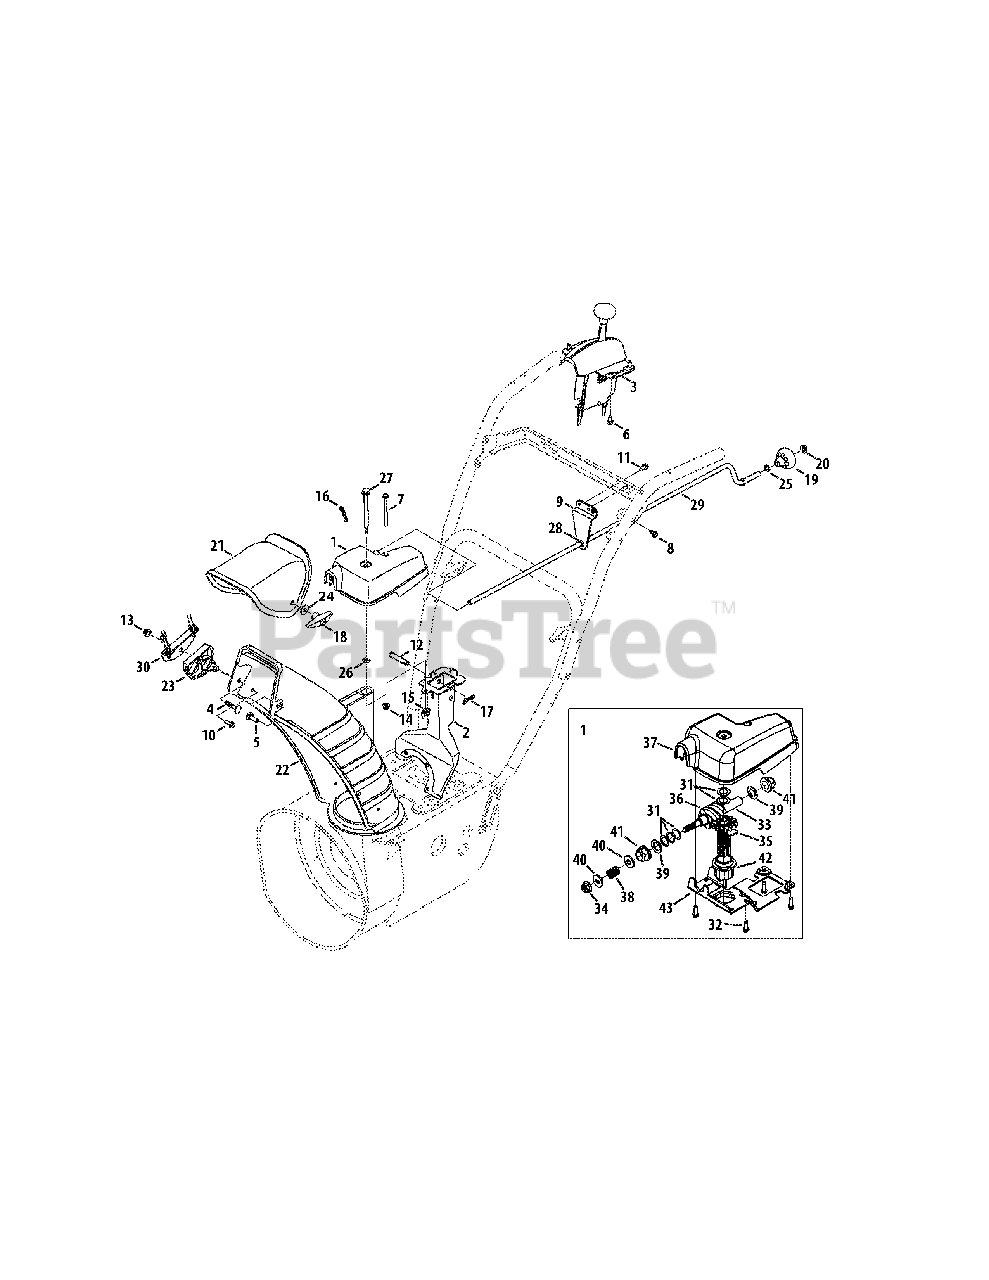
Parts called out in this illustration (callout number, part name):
1	Chute Rotation Gearbox
2	Chute Support Bracket (small block)
3	Chute Control, 2-Way
4	Carriage Bolt, 5/16-18 x .750
5	Bolt, Carrier, 5/16-18 x 1.00
6	Screw, Hi-Lo, 1/4-15 x 0.50
7	Hex Head Screw, 1/4-20 x 3.00
8	Screw, TT, 1/4-20 x .500
9	Support Rod Bracket
10	Screw, Hi-Lo, 1/4-15 x 0.750
11	Screw, 1/4-20 x .625
12	Clevis Pin, 3/8 x 1.87
13	Nut, Flange Lock, 5/16-18
14	Nut, Flange Lock, 1/4-20
15	Wing Nut, 1/4-20
16	Internal Cotter Pin
17	Bow-Tie Cotter Pin
18	Wing Knob, 5/16-18
19	Shift Knob, .390
20	Push Cap, 3/8
21	Upper Chute
22	Lower Chute, 5.0
23	Cable Guide, Chute Tilt
24	Washer, Flat, .349 x .879
25	Flat Washer, .375 x .738 x .063
26	Washer, Flat, .25 x .630
27	Shoulder Screw, .312 x 3.5 x 1/4-20
28	Plastic Bushing, .380 ID
29	Chute Crank
30	Cable Bracket
31	Shim Washer, .632 x 1.00 x .010
32	Screw, 12-16 x .75
33	Worm Shaft
34	Flange Lock Nut, 3/8-16
35	Gear Assembly
36	Worm
37	Gear Cover
38	Compression Spring, .39 x .60 x .88
39	Flat Washer, .625 x 1.0 x .067
40	Flat Washer, .380 x .93 x .110
41	Hex Bearing
42	Flange Bearing
43	Gear Bracket
